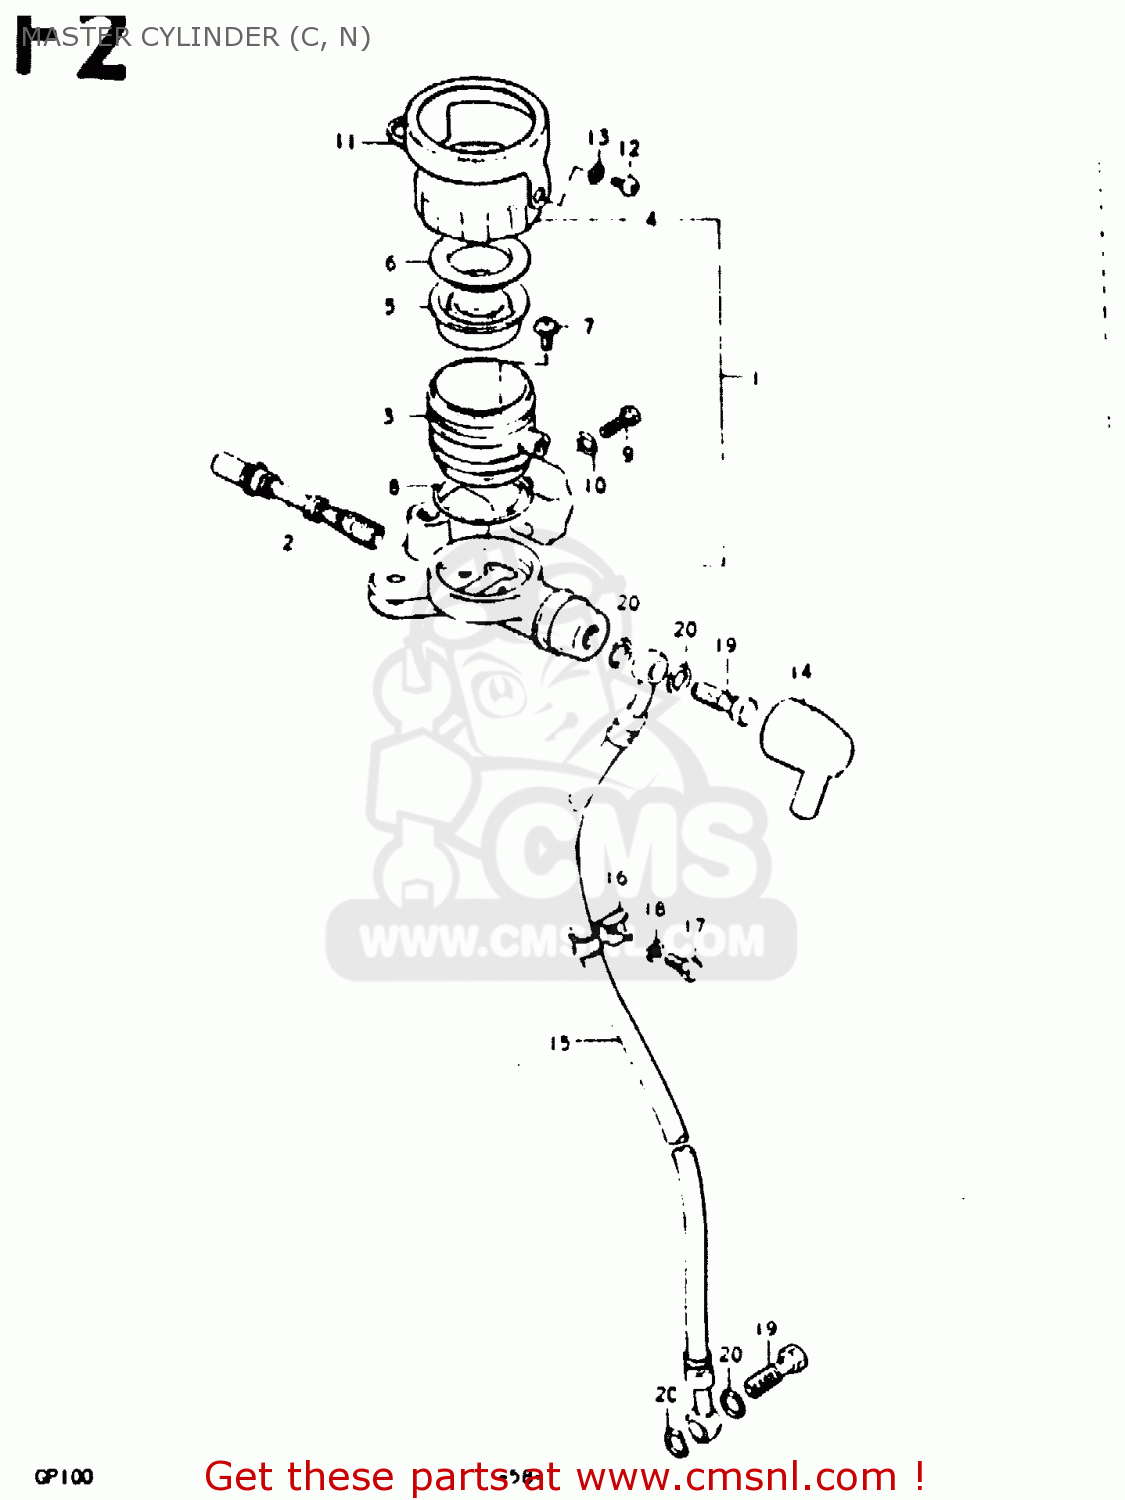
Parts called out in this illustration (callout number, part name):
1	CYLINDER ASSY, MASTER
2	PISTON & CUP SET
3	RESERVOIR
4	CAP,MASTER CYLINDER,REAR
5	DIAPHRAGM
6	PLATE
7	SCREW,MASTER CYLINDER
8	O RING
9	BOLT
10	WASHER
11	LOCK PLATE, CAP
12	SCREW
13	LOCK WASHER
14	BOOT,MASTER CYLINDER
15	HOSE, BRAKE
16	CLAMP,BRAKE HOSE
17	BOLT
18	LOCK WASHER
19	BOLT UNION
20	WASHER
